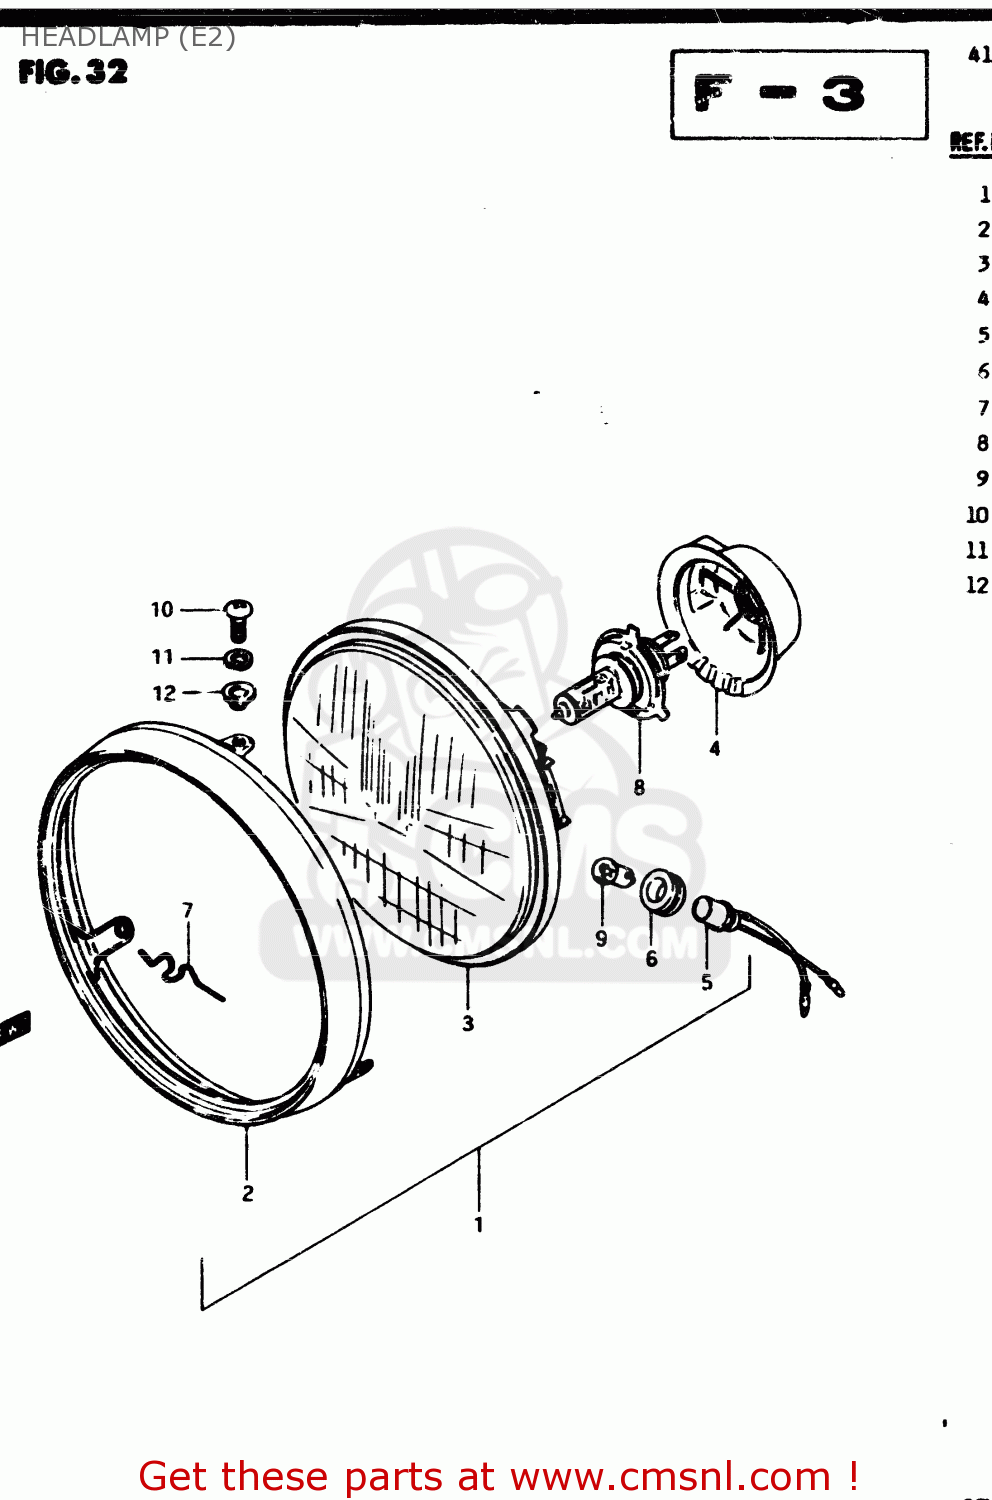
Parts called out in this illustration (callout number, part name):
1	HEADLAMP ASSY
2	RIM
3	LAMP UNIT
4	COVER,SOCKET
5	SOCKET
6	JOINT,RUBBER
7	SPRING
8	BULB(12V60/55W,H4)
9	BULB(12V3.4W,STANLEY,A72A)
10	SCREW
11	WASHER,LOCK
12	WASHER
